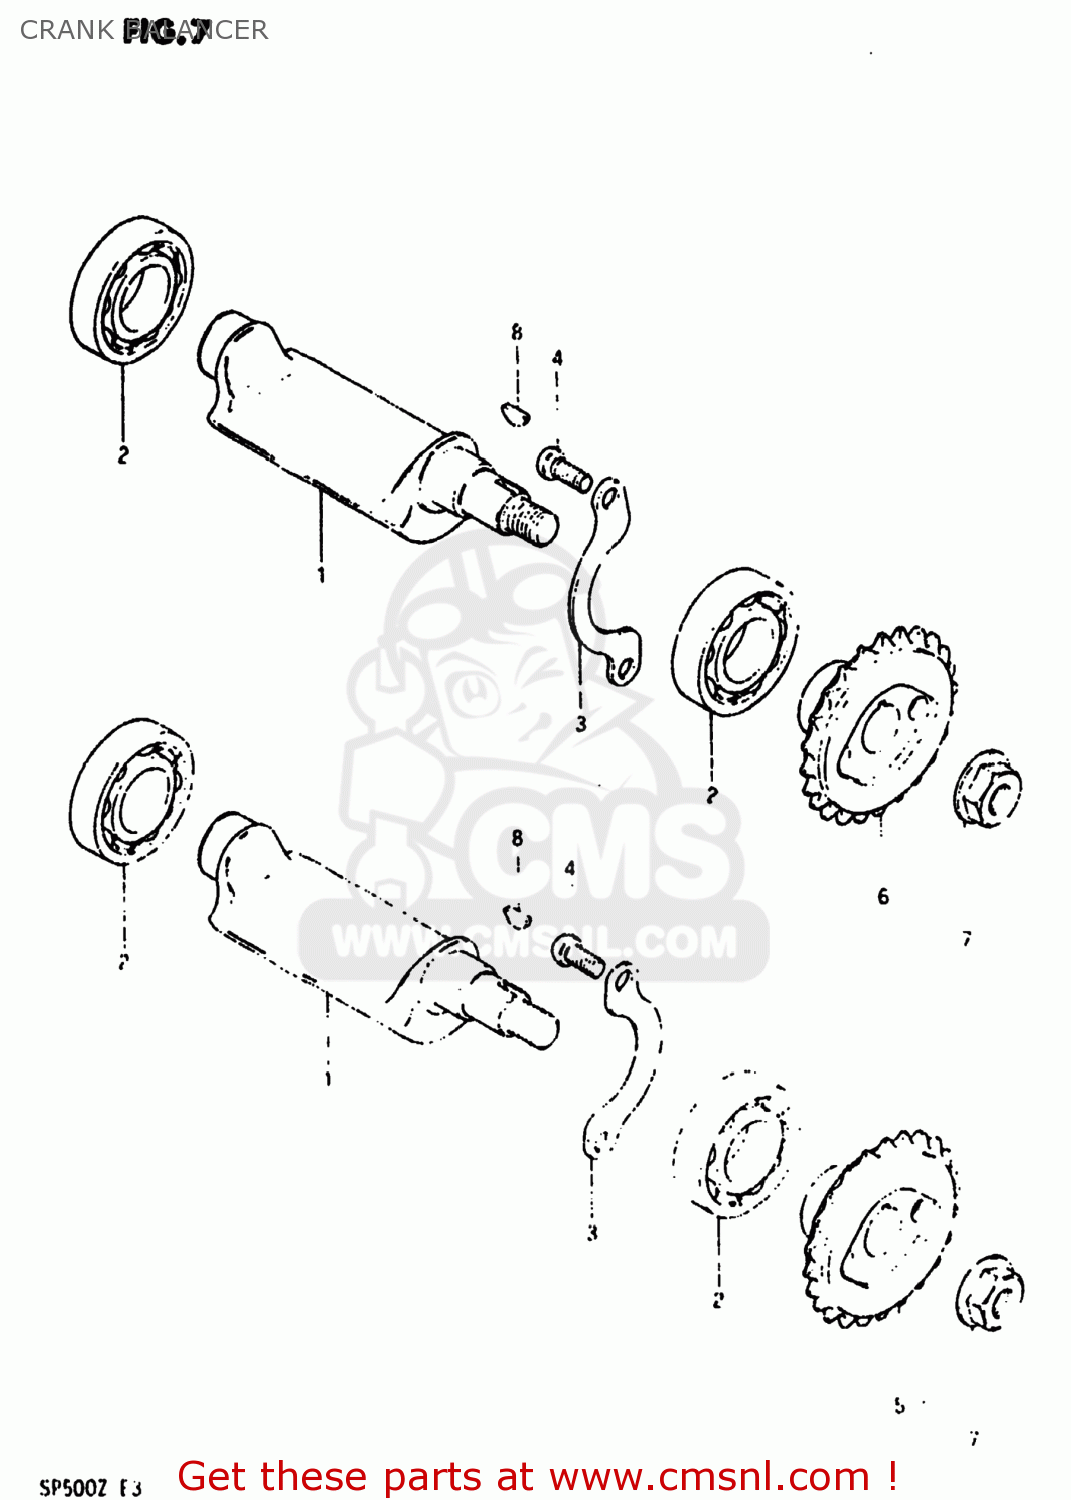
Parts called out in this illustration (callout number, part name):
1	BALANCER,CRANKSHAFT
2	BEARING
3	RETAINER,CRANK BAL BEARING
4	SCREW 6X12
5	SPROCKET,BALANCER DRIVE
6	SPROCKET,BALANCER DRIVE
7	NUT
8	KEY
